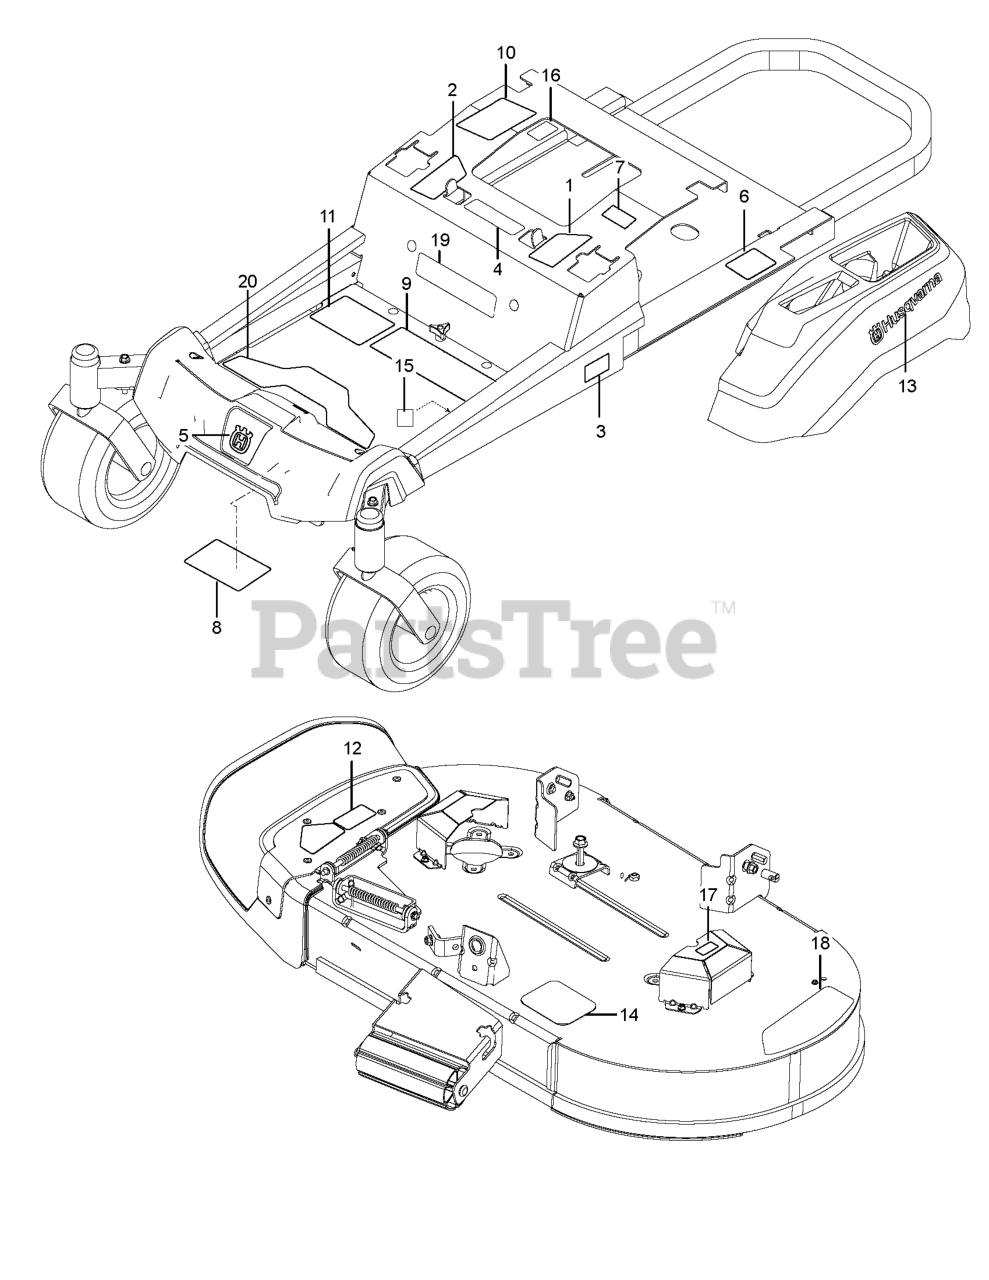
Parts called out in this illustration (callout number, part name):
1	DECAL.ZTR.RZ.THRTL/PRKBRK.V2.L
2	DECAL.ZTR.RZ.THRTL/PRKBRK.V2.R
3	DECAL.ZTR.SIDRAIL.Z242F.HUS
4	EURO DECAL-BATTERY WARNIN6
5	DECAL.BADGE.55MM.CROWNH.HUSQ
6	DECAL, DO NOT TOW
7	DECAL, EXITING MOWER
8	DECAL, SERVICE
9	DECAL ZTR WARNING DECAL DECAL.
10	DECAL.WARNING.CUST.RESP.E85.
11	DECAL.ZTR.STARTINSTRCT.CHOKE15
12	DECAL.TRACT/ZTR.DECKWARN.HUSQ
13	DECAL.HUSQVARNA.210MM
14	DECAL, BELT ROUTING
15	DECAL.80.DBA.AUSTRALIA
16	DECAL CERTIFICATION DECAL EMCC
17	DECAL.DECK.CLEARCUT.NOSTEP
18	DECAL DECK DECAL DECAL.42DECK.
19	DECAL ZTR BRAND GRAPHIC DECAL.
20	PAD.RZ.FOOTREST.PLATE
